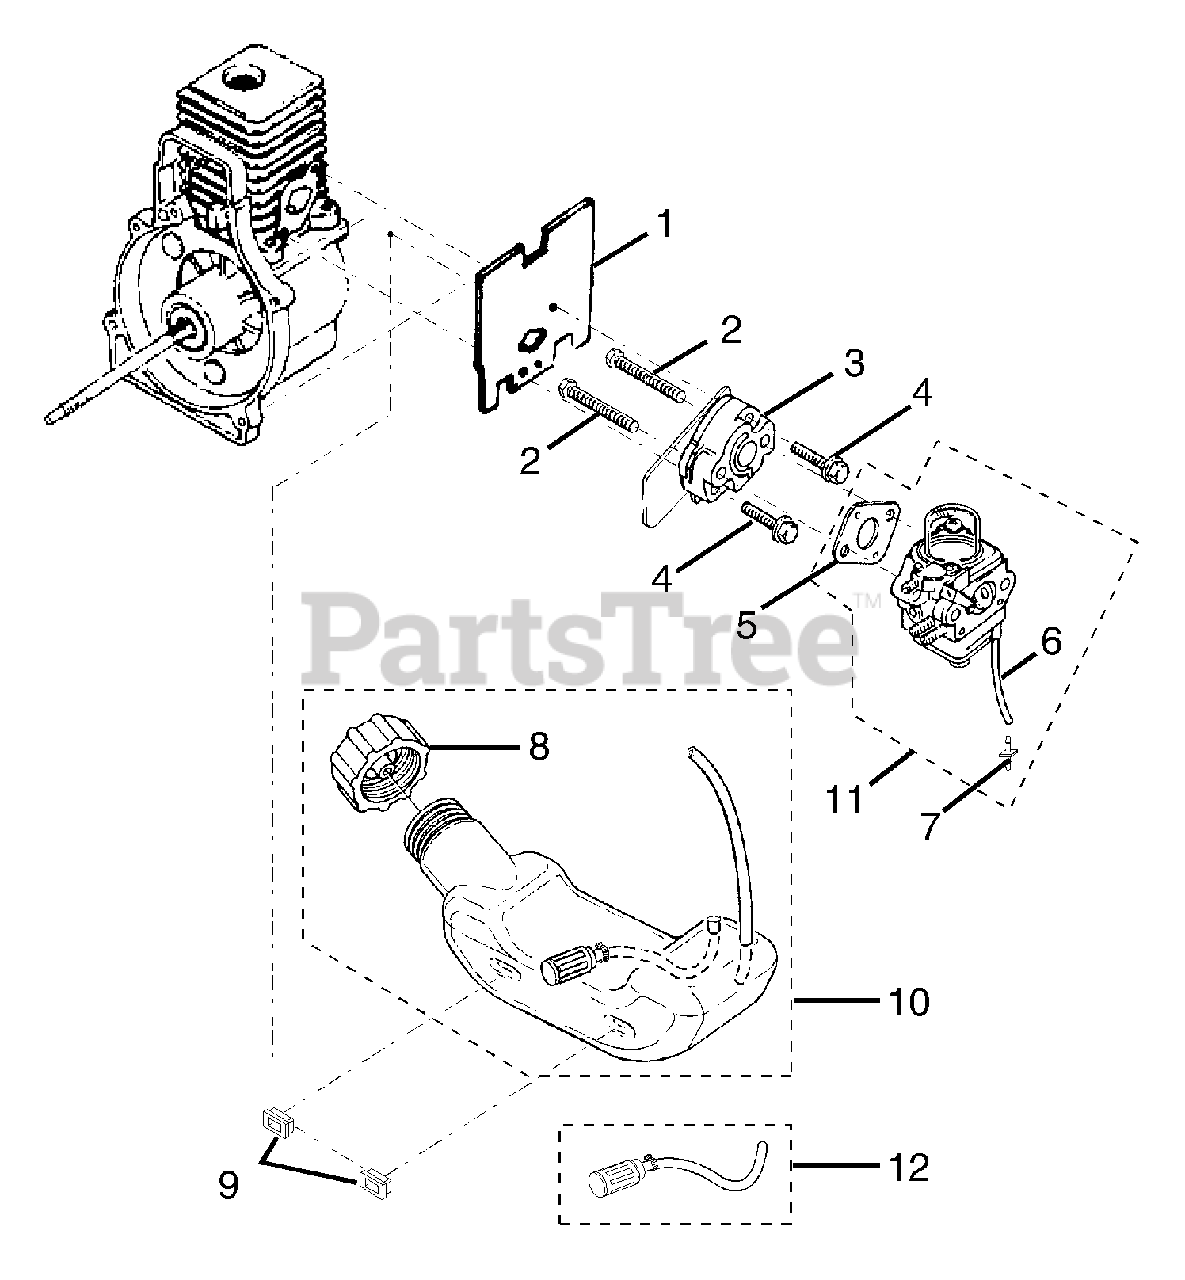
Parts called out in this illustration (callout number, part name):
1	HEAT DAM GASKET
2	CARBURETOR BOLT
3	HEAT DAM
4	PAN HEAD SEMS SCREW
5	CARBURETOR GASKET
6	RUBBER HOSE (63.5 mm)
7	INLINE FUEL FITTING
8	FUEL CAP
10	FUEL TANK ASSEMBLY
11	CARBURETOR ASSEMBLY KIT
12	FUEL FILTER KIT
